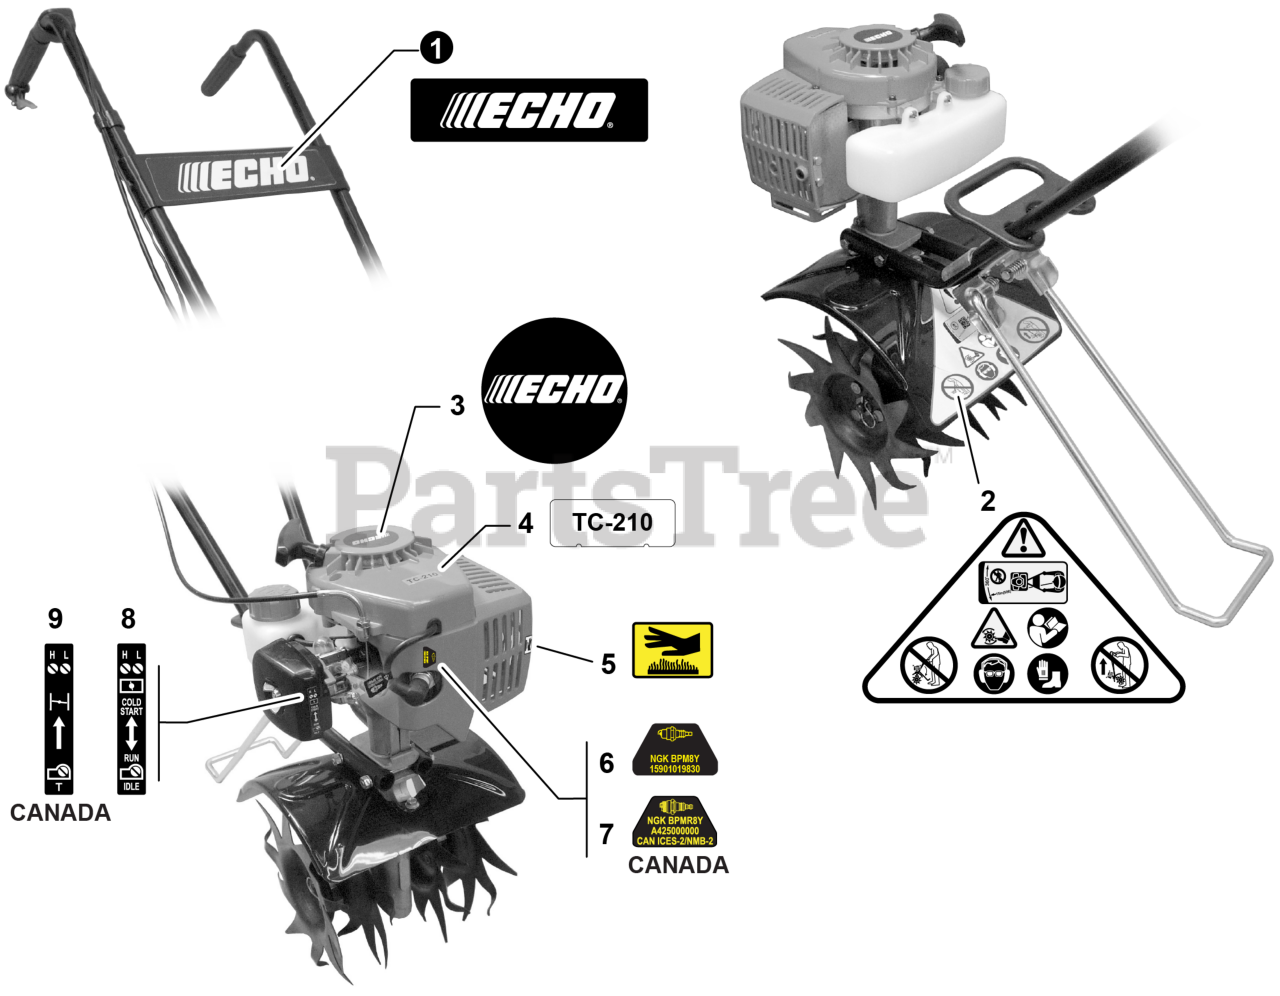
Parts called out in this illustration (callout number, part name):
1	LABEL - ECHO
2	LABEL - CAUTION
3	LABEL - STARTER - ECHO
4	LABEL - MODEL
5	LABEL - CAUTION - HOT
6	LABEL - SPARK PLUG - BPM8Y
7	LABEL - SPARK PLUG - BPMR8Y
8	LABEL - CHOKE
9	LABEL - CHOKE
